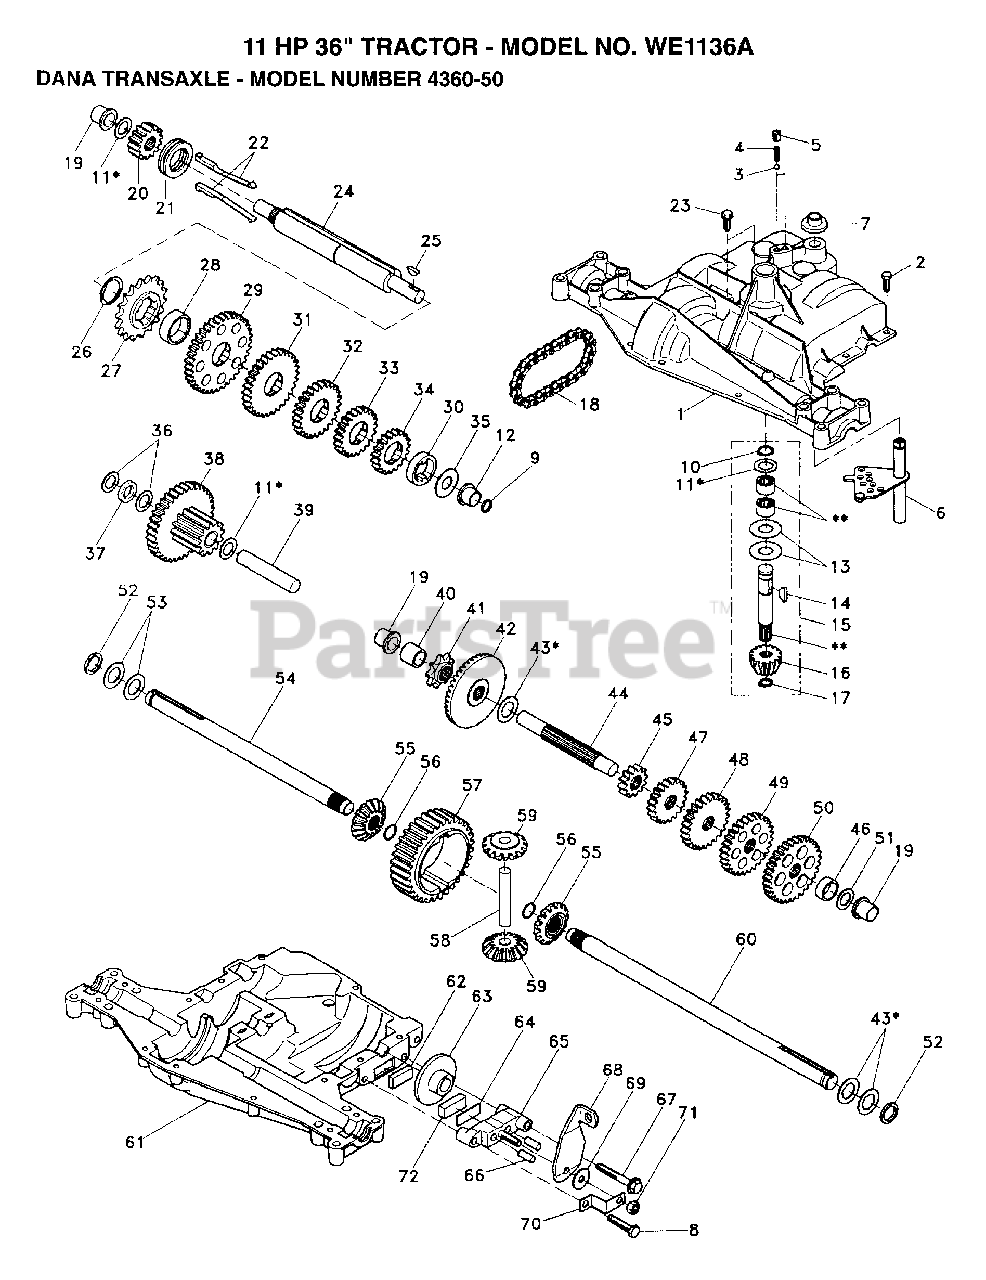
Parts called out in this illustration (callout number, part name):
4	"SPRING, DETENT LT"
5	"SCREW, SET LT"
6	KIT SHIFTER ASM
7	SHIFTER BOOT
8	"SCREW, TAPPING LT"
9	SQUARE RING
10	RETAINING RING LT
11	ASM KIT SHIM 4689
12	"FLANGE, BEARING"
13	WASHER T
14	WOODRUFF KEY
15	AS KIT INPUT SHFT
16	PINION 14T T
17	"RING,RETAINING LT"
18	"CHAIN,24 PTCH LT"
19	BEARING.FLNG.5510
20	GEAR SPUR 14T
21	COLLAR CLUTCH
22	ASM KIT CLTCH KEY
23	SCREW TAP W/SEAL
24	SHAFT INTERM
25	WOODRUFF KEY
26	"RING,RETAINING LT"
27	SPROCKET 18T T
28	SPACER YT
29	KIT.GEAR.12/37TH
30	SPACER
32	GEAR 25T LT
33	GEAR SPUR 22 TT
34	SPUR GEAR 19T
35	"WASHER, PLAIN LT"
36	WASHER 025
37	SPACER
38	ASSM GEAR COMB
39	SHAFT IDLER
40	SPACER T
41	SPROCKET 9T LT
43	ASM KIT SHIM
44	SHAFT T
48	"GEAR, SPUR 25T LT"
49	GEAR 28T T
50	"GEAR, SPUR 31T LT"
51	WASHER 060
52	NEOPRENE WASHER
53	WASHER 031
55	GEAR 15T T
56	"RING,RETAINING LT"
58	SHAFT T
59	GEAR 1ST T
62	PUCK T
63	BRAKE DISC. T
64	SPACER LT
66	PIN T
69	WASHER LT
71	NUT.LOCK.5/16-24
72	PUCK T
